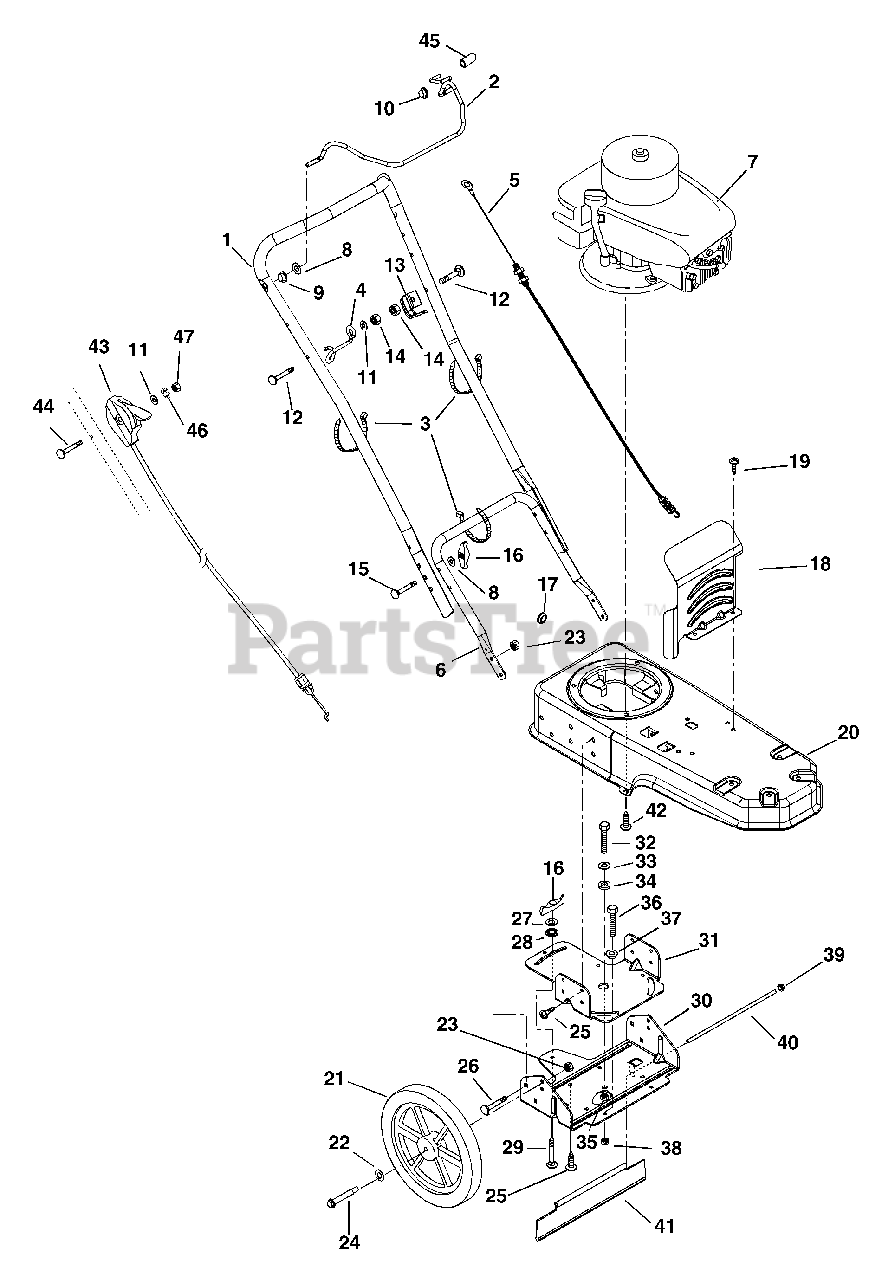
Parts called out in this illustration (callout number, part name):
1	Handlebar-Upper
2	Bail-Clutch Control
3	Cable-Tie
4	Guide-Pullcord
5	Cable-Control
6	Handlebar-Lower
7	Kit-6 H.P.-Tecumseh Engine
8	Washer-Flat-Steel .344 x .688 x .065
9	Bushing-Flange .325 x .444 x .440 x .560
10	Nut-Push .25
11	Washer-Flat-Steel .281 x .62 x .065
12	Bolt-Round Head Extra Long Square Neck .25-20 x 1.25
13	Cable-Anchor
14	Nut-Locking-Center .25-20
15	Bolt Round Head Square Neck Full Thread .31-18 x 2.00 Grade 5
16	Knob-Wing .312-18
17	Grommet .50 I.D.
18	Guard-Engine
19	Screw-Tapping .38-16 x .50
20	Frame-Trimmer
21	Wheel 16 x 1.75 x .50
22	Washer-Flat-Steel .52 x .827 x .062
23	Nut-Locking-Center .38-16
24	Bolt-Shoulder .38-16 x 2.50
25	Screw-Tapping .38-16 x .75
26	Bolt-Round Head Square Neck .38-16 x .75 Grade 5
27	Washer-Flat-Steel .38 x .875 x .083
28	Nut-Push .312
29	Bolt-Round Head Square Neck .31-18 x 1.00 )
30	Bracket-Axle Swivel
31	Base-Swivel
32	Bolt-Hex .50-13 x 1.00 Grade 5
33	Washer-Flat-Steel .562 x 1.38 x .109
35	Nut-Locking-Center .50-13
36	Bolt-Hex .31-18 x 1.00
37	Bushing Flange .312 x .500 x .344 x .880
38	Nut-Locking-Center .31-18
39	Nut-Push .312
41	Guard-Rear-Swivel
42	Screw-Tapping .38-16 1.00
43	Throttle-Control
44	Bolt-Round Head Square Neck .25-20 x 2.00
45	Cap-Vinyl .25 I.D.
46	Washer-Lock .25 x .062
47	Nut-Hex .25-20
